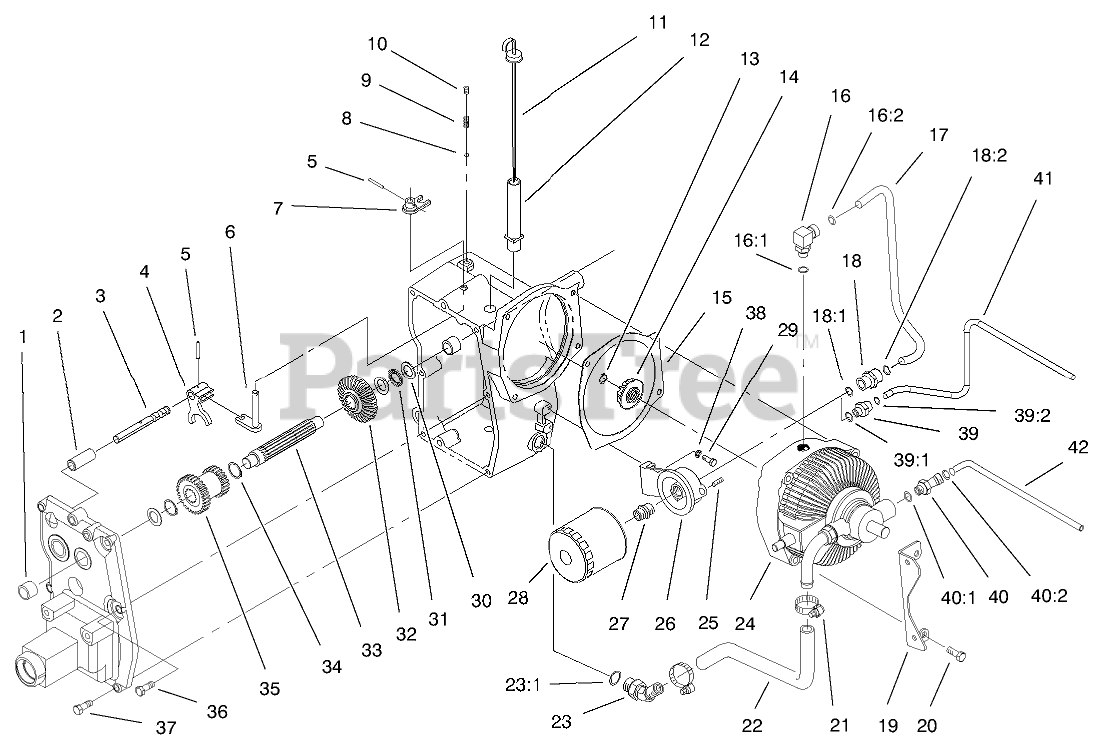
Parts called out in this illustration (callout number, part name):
1	BEARING-NEEDLE
2	TUBE-RAIL, SHIFTER
3	RAIL-SHIFT
4	FORK-HI / LO SHIFT
5	PIN-ROLL
6	ARM-SHIFTER
7	SHIFT-HI / LO
8	BALL-DETENT
9	SPRING-DETENT, SHIFT
10	SCREW-SET, HSH
11	DIPSTICK
12	TUBE-DIPSTICK
13	RING-SNAP, EXTERNAL
14	PINION-BEVEL
15	GASKET
16	FITTING -HYD, 90 DEGEE
16:1	O-RING
16:2	O-RING
17	TUBE-HYD
18	FITTING-STRAIGHT
18:1	O-RING
18:2	O-RING
19	PLATE-BRACKET, SUPPORT
20	SCREW-HH
21	CLAMP-DRIVE, WORM
22	HOSE-SUCTION
23	FITTING-HOSE
23:1	O-RING
24	TRANSMISSION-HYDRO
26	BASE-FILTER
27	FITTING
28	OIL FILTER ASM
29	SCREW-HH
30	WASHER-THRUST
31	BEARING-THRUST
32	GEAR-BEVEL
33	SHAFT-INPUT
34	RING-RETAINING
35	GEAR-HI / LO
36	SCREW-HH
37	SCREW-HH
38	WASHER-LOCK
39	FITTING-HYD. STRAIGHT
39:1	O-RING
39:2	O-RING
40	FITTING-HYD, 45 DEGREE
40:1	O-RING
40:2	O-RING
41	TUBE-HYD
42	TUBE-HYD
